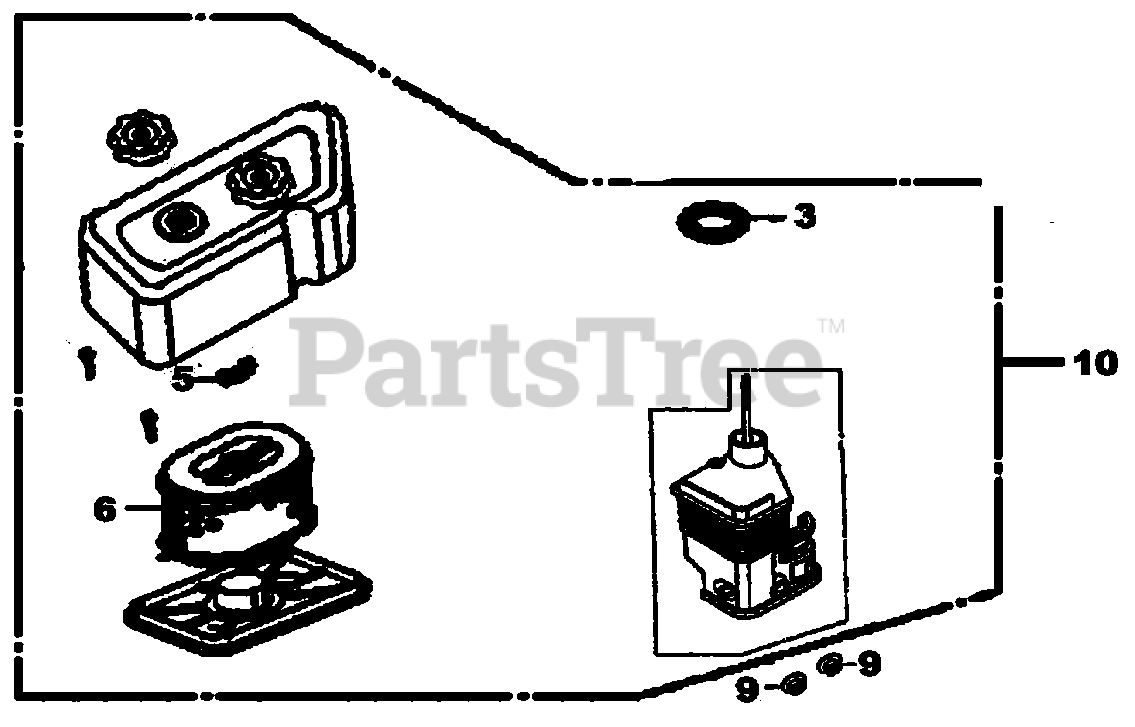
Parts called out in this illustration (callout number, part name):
3	GASKET, ELBOW
5	NUT, TOOL BOX SETTING
6	ELEMENT ASSY., AIR CLEANER
9	NUT, FLANGE
10	CLEANER ASSY., AIR
